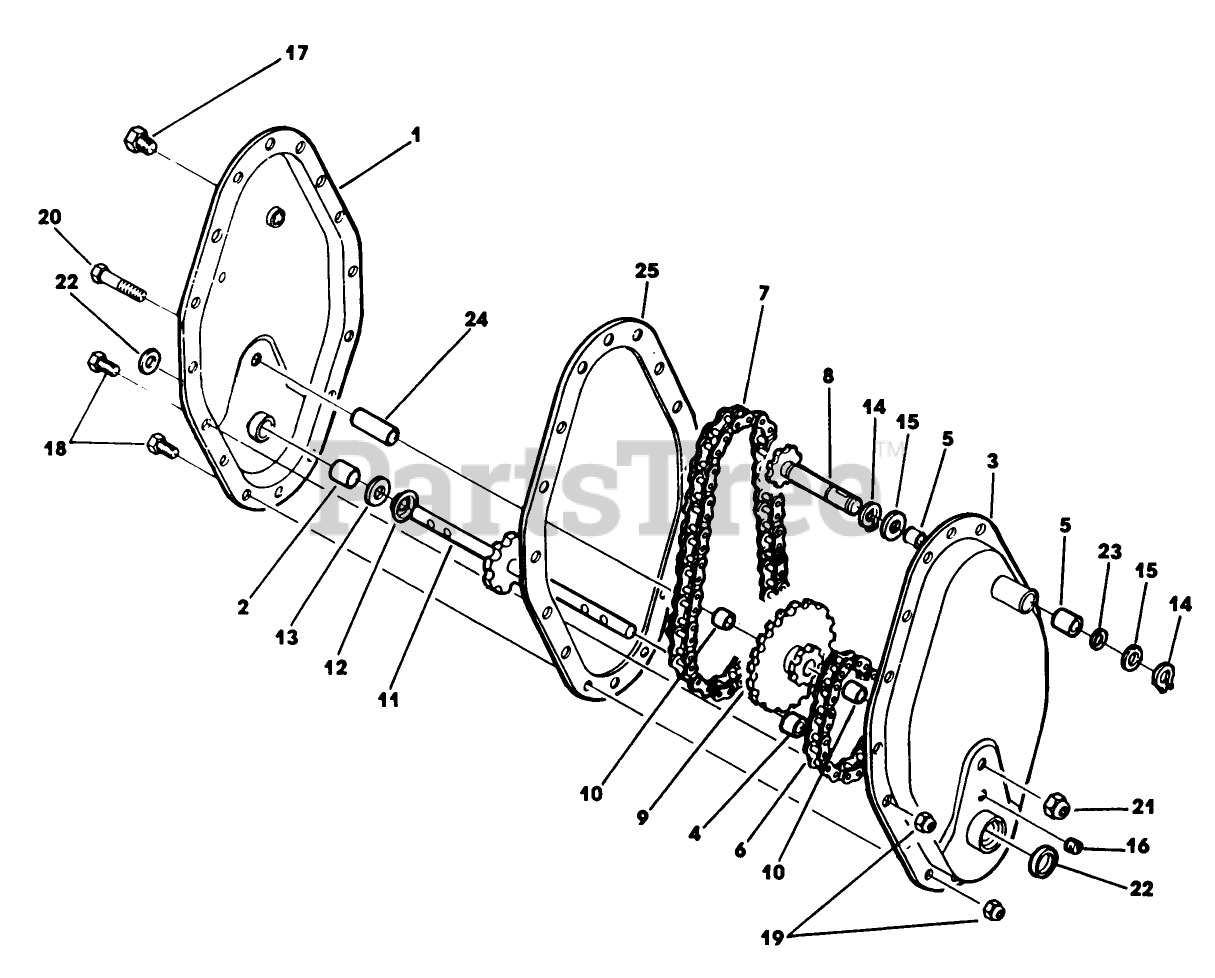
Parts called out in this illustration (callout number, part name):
7	CHAIN - UPPER
9	SPROCKET AY.
12	SPACER CUP
13	SHIM-GEAR
14	RING-RETAINING
18	SCREW-HH
19	NUT-LOCK, CONE
21	NUT-LOCKING
22	SEAL
23	SEAL-INPUT SHAFT
24	SLEEVE - IDLER
